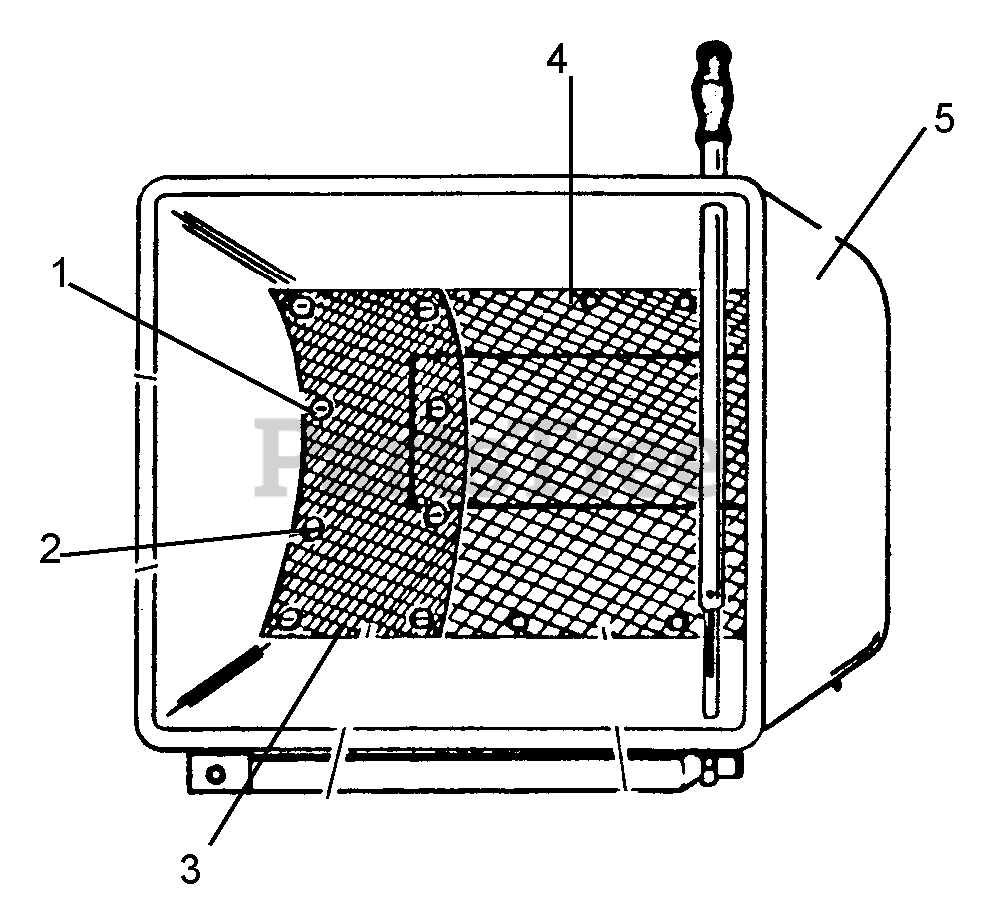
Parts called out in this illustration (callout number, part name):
1	@SCR-MCH 10-24X.50 HWH YWZC
2	@WSHR-FL-STL.219X.50X.049 YWZC
3	@NUT-LK-NYL 10-24 W/INSRT YWZC
4	SCREEN
